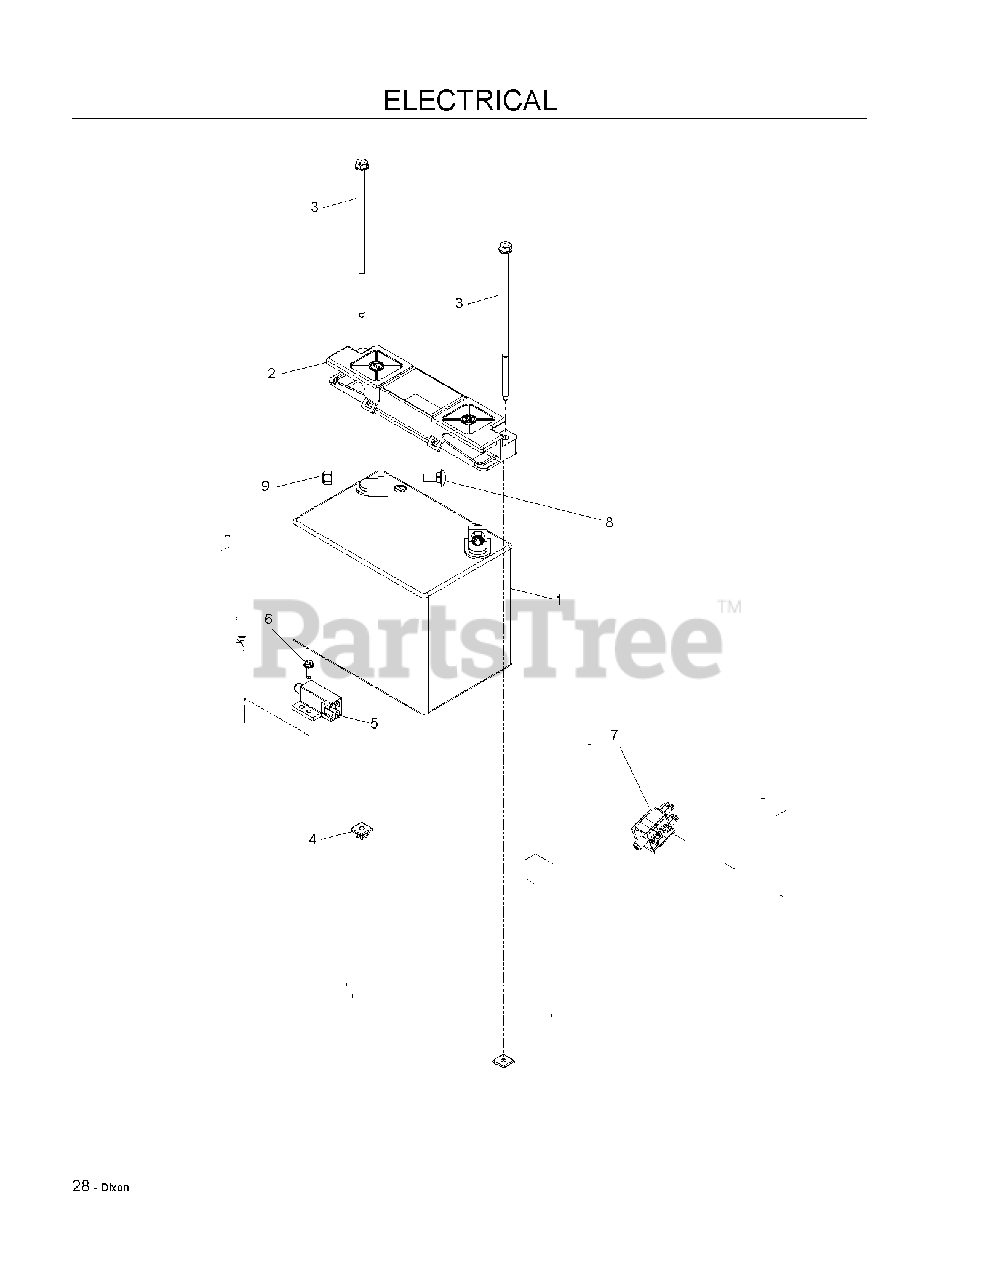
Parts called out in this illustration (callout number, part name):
1	BATTERY, 12 V 330 AMP TBR
2	BATTERY HOLD DOWN
3	BOLT - 1/4-20 X 7.5
4	PUSH NUT-NYLON
5	SWITCH, INTERLOCK
6	SCREW #10 X 1/2 SELF TAPPING
7	SWITCH, BRAKE 3P
8	BOLT 5/16C X 3/4" CARRIAGE
9	5/16-18 NYLOC FLANGE NUT
